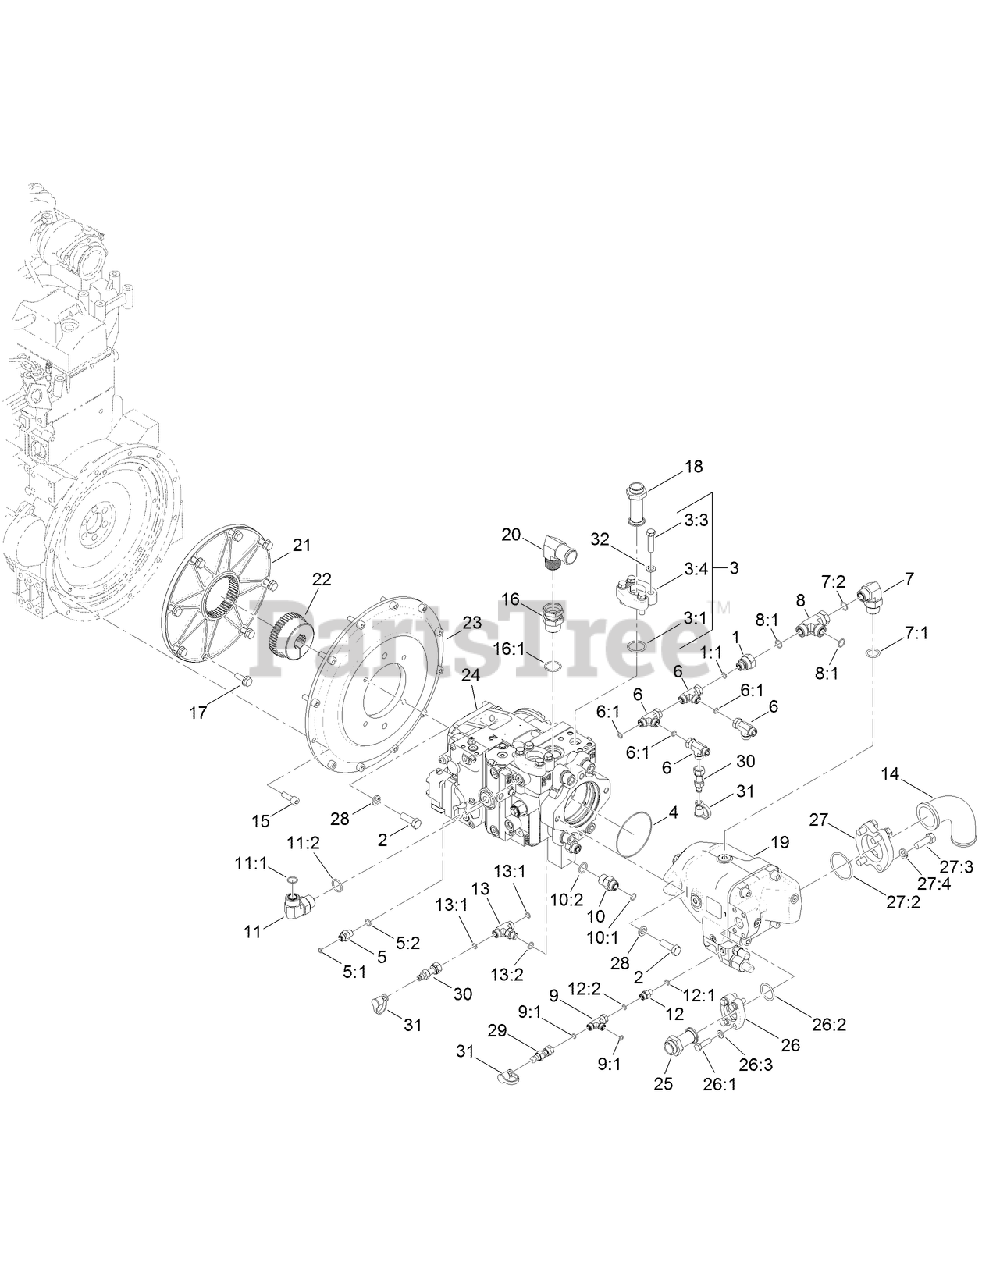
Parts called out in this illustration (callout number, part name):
1	FITTING-HYD
1:1	O-RING
2	SCREW-HH
3	HYD FLANGE KIT
3:1	O-RING
3:3	SCREW-HH
4	O-RING
5	FITTING-STRAIGHT
5:1	O-RING
5:2	O-RING
6	FITTING-TEE, SWIVEL NUT
6:1	O-RING
7	FITTING-ELBOW 90
7:1	O-RING
7:2	O-RING
8	FITTING-HYD, TEE
8:1	O-RING
9	FITTING-HYD
9:1	O-Ring
10	FITTING-STRAIGHT
10:1	O-RING
10:2	O-RING
11	FITTING-ELBOW-90
11:1	O-RING
11:2	O-RING
12	FITTING-STRAIGHT
12:1	O-RING
12:2	O-RING
13	ADAPTER
13:1	O-RING
13:2	O-RING
14	END-HOSE
15	SCREW-HSH
16	FITTING-STRAIGHT
16:1	O-RING
17	SCREW-HHF
18	ADAPTER-FLANGE, STRAIGHT
19	HYD LOAD SENSE PISTON PUMP ASM
20	FITTING-ELBOW, 90
21	COUPLING-DRIVE
22	HUB-STEEL
23	COVER-FLYWHEEL, PUMP MOUNT
24	HYD HYDROSTAT PUMP ASM
25	ADAPTER-FLANGE, STRAIGHT
26	SPLIT FLANGE KIT
26:1	SCREW-HH
26:2	O-RING
26:3	WASHER-LOCK
27	FLANGE KIT
27:2	O-RING
27:3	SCREW-HH
27:4	WASHER-LOCK
28	WASHER-LOCK
29	NIPPLE-TEST
30	NIPPLE-TEST
31	CAP-DUST
32	WASHER-LOCK
